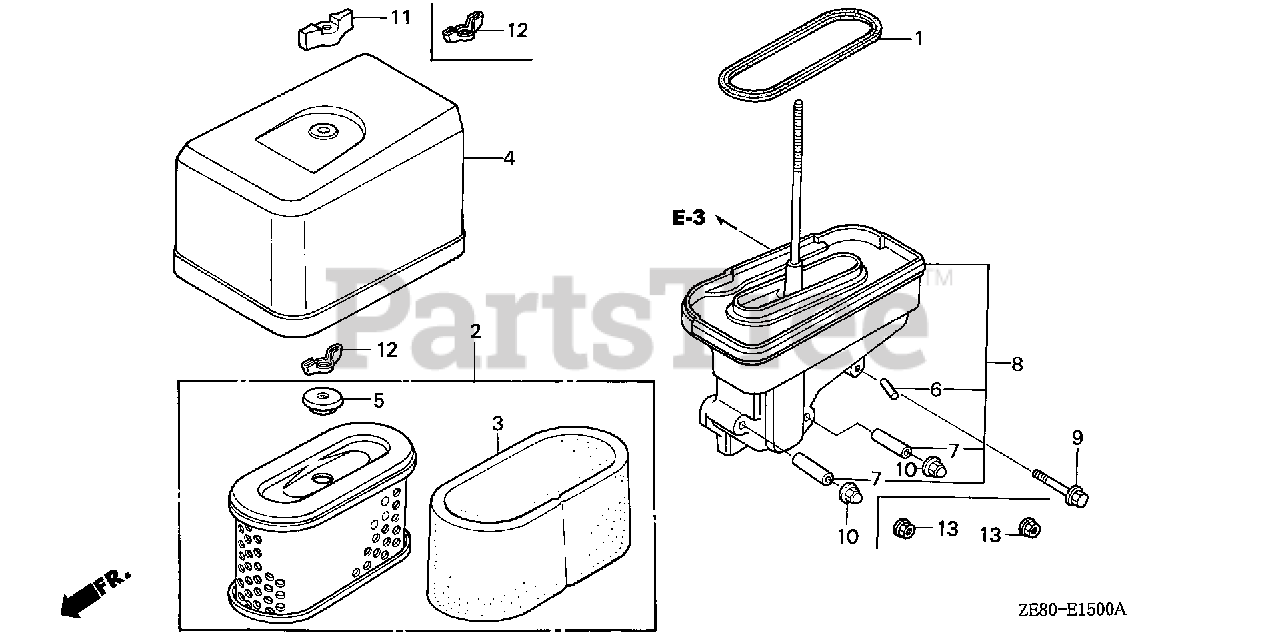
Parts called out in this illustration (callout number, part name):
1	GASKET, ELBOW
2	ELEMENT, AIR CLEANER (METAL BASE)
3	FILTER (OUTER)
4	COVER, AIR CLEANER (DUAL)
5	GROMMET, AIR CLEANER
6	COLLAR, AIR CLEANER
7	COLLAR, AIR CLEANER
8	ELBOW, AIR CLEANER
9	BOLT, FLANGE (6X35) (CT200)
10	NUT, CAP (6MM)
11	WINGNUT
12	NUT, TOOL BOX SETTING
